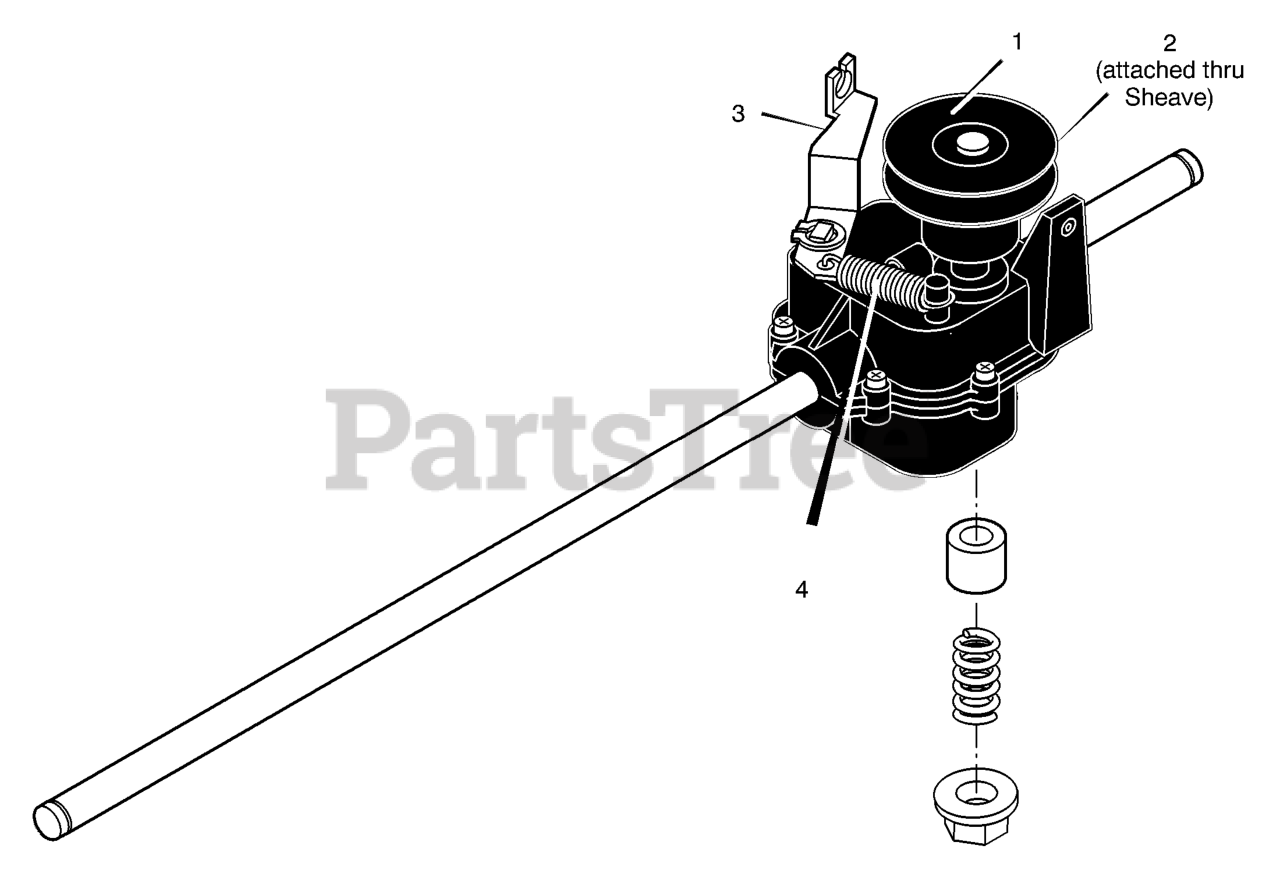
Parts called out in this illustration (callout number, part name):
2	Attachment Pin, Pulley
3	Clutch Lever Assembly
4	Spring, Clutch Return
